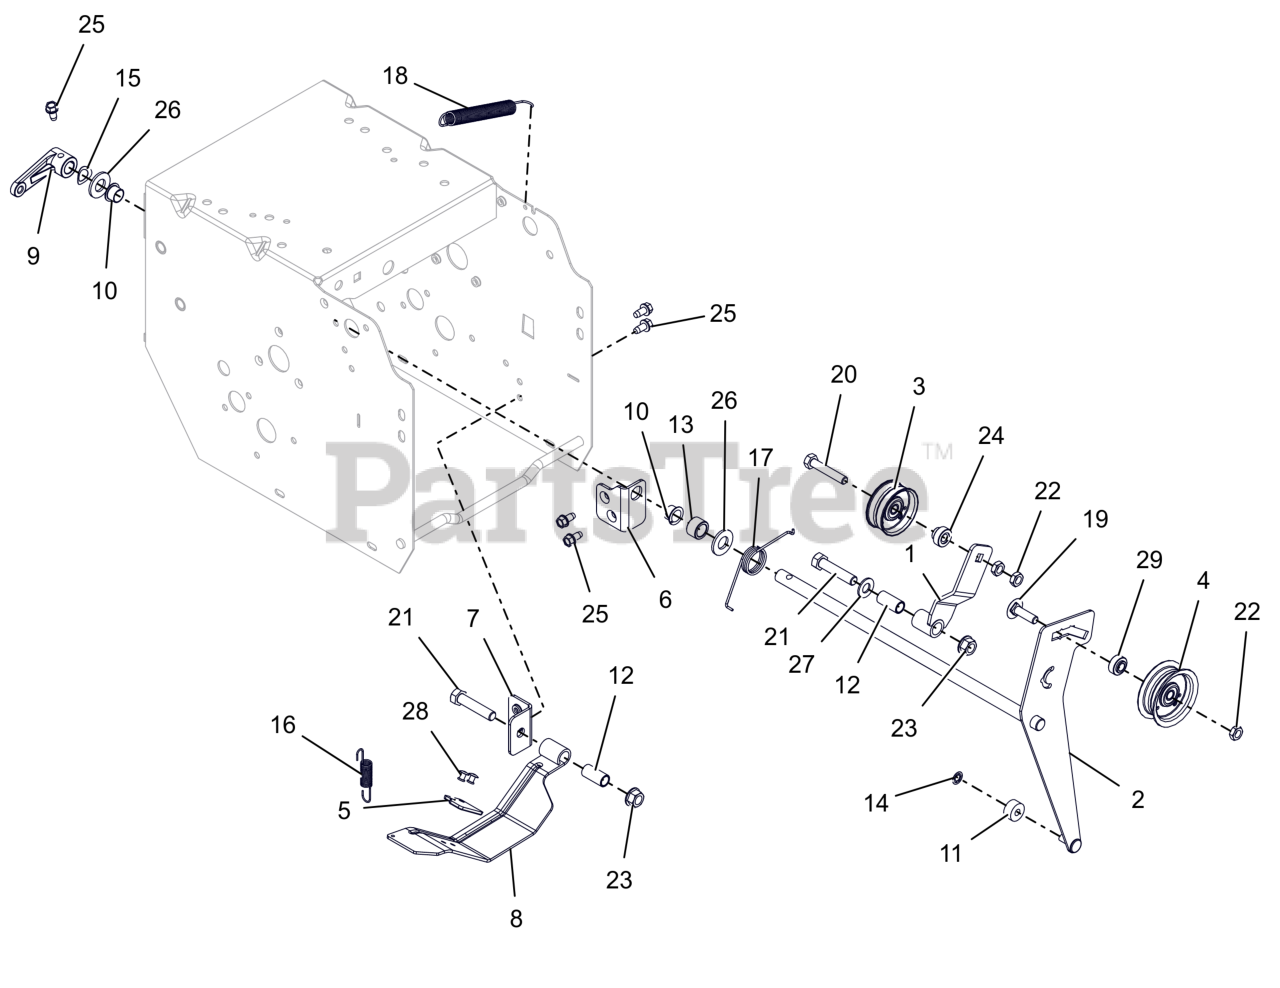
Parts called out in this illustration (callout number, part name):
1	ARM, TRACTION IDLER
2	WELDMENT, ATTACHMENT IDLER ARM
3	IDLER, FLAT - 1.875"
4	IDLER, FLAT - 2.00"
5	PAD, BRAKE
6	BRACKET, MOUNT - IDLER ARM
7	BRACKET, MOUNT - BRAKE
8	BRAKE ARM W/PAD
9	ARM, CLUTCH - ATTACHMENT
10	BUSHING, POLYLINER-.50 SPLIT
11	BSHG,SLV .265 X .625 X .375
12	BSHG-SLV .385X.500X1.045
13	BSHG-SLV .510X.751X.475
14	RG-RTNG-EXT .250X.010
15	WSHR-WAVE .50X.75X.015 .13FRHT
16	SPRING-EXT .437 X .438 X 2.64
17	SG-TORS .075 X .955
18	SPRING, EXTENSION
19	BLT, RHSSN .31-18X1.125 G5 ZCC
20	BLT, HEX .31-18X1.75 G5 ZCC
21	BLT, HEX .38-16X1.75 G5 ZCC
22	NUT-LK-CTR-JAM .312-18 GB ZCC
23	NUT-LK-TOP-FLG .38-16 ZC120
24	SPCR, BRG .315X.500X.481X.281
25	SCR-TAP .25-20X.50 HWH ZCC
26	WSHR,FLT .531X1.062X.095 ZCC
27	WSHR,FLT .406X.812X.065 ZCC
28	RVT, POP .1875 ZCC
29	SPCR, BRG .315X.500X.358X.281
